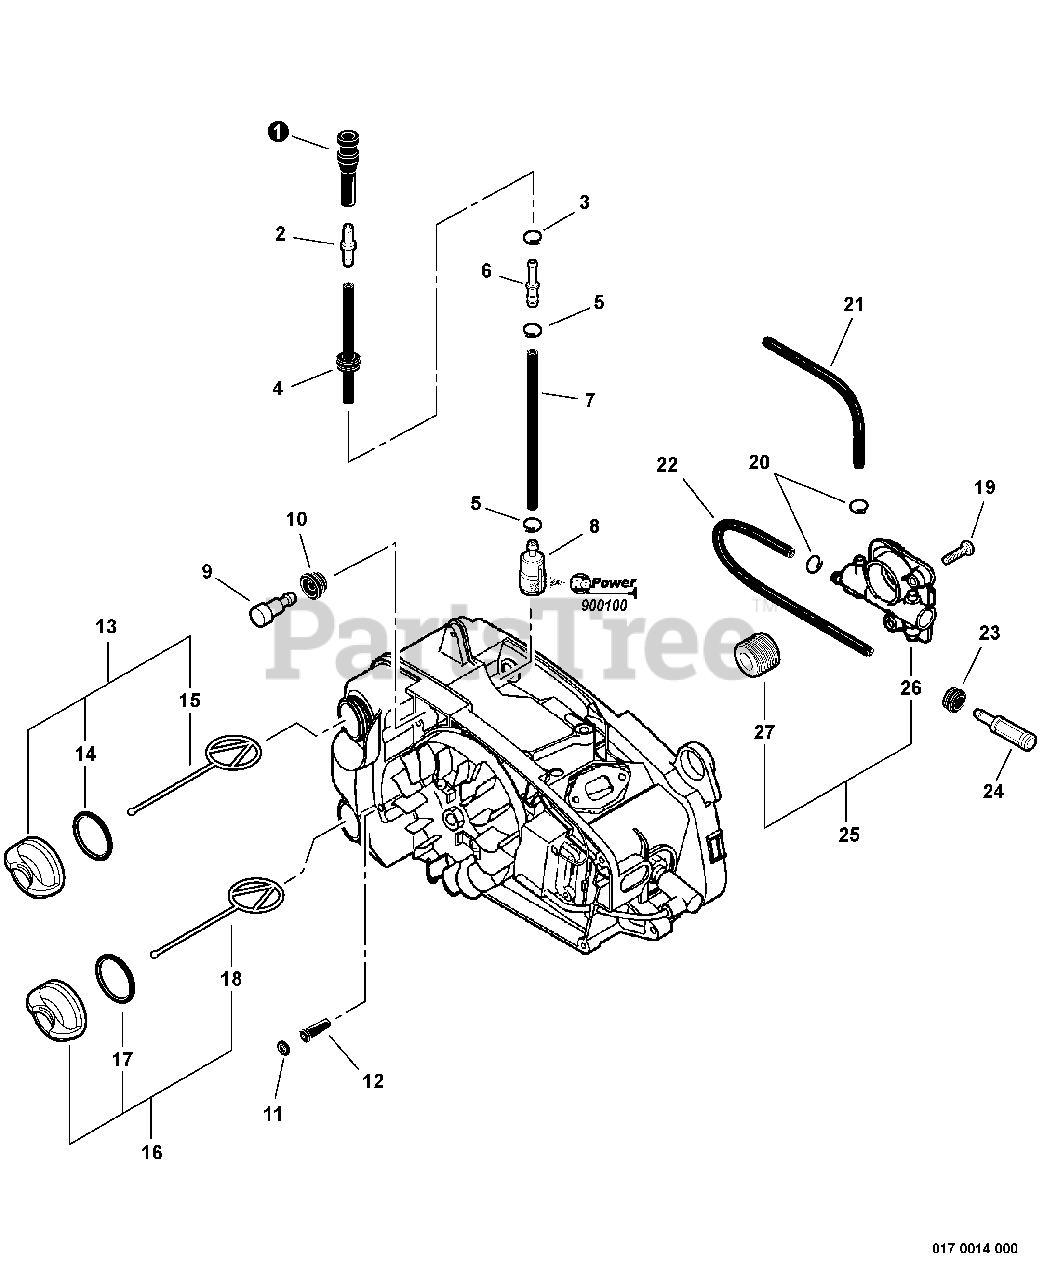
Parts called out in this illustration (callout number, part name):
1	PIPE, FUEL
2	CONNECTOR, PIPE
4	PIPE ASSY, FUEL
5	CLIP Ø6
6	CONNECTOR, PIPE Ø5ר3.5
7	PIPE, FUEL 3×5×95
8	FILTER, FUEL
9	VENT ASSY
10	GROMMET, FUEL
11	O-RING S-4
12	VENT ASSY
13	CAP ASSY, FUEL - ORANGE
15	CONNECTOR, CAP L= 60 MM
16	CAP ASSY - BLACK
17	O-RING 18
18	CONNECTOR, CAP L= 60 MM
19	SCREW 4×12
20	CLIP Ø6.5 MM
21	PIPE 3×6×90 MM
22	PIPE 3×6×185 MM BLACK
23	GROMMET
24	FILTER, OIL
25	AUTO-OILER KIT
26	AUTO-OILER ASSY
27	GEAR, WORM
28	REPOWER TUNE-UP KIT
